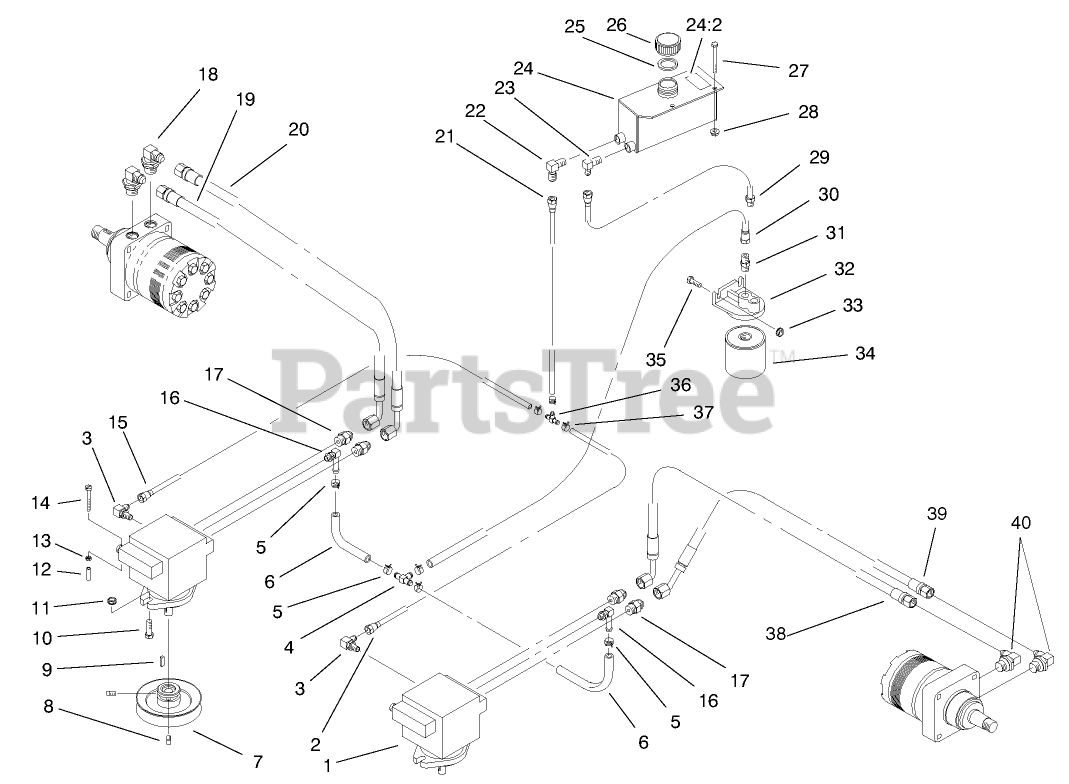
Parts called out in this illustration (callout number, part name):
1	Pump-Hydro
2	Hose-Low Pressure
3	Elbow
4	Fitting
5	Clamp-Hose
6	Hose-Low Pressure
7	Sheave w/Hub
8	SCREW-SET, SQH
9	Key
10	SCREW-HH
11	NUT-HHF, WHIZ
12	Grip
13	NUT-LOCK, NI
14	Screw-PPH
15	Hose-Low Pressure
16	Elbow
17	Adapter
18	Elbow 90
19	Hose
20	Hose
21	Hose
22	Elbow
23	Elbow
24	HYDRAULIC TANK ASM
24:2	Decal-HydraulicTank, Hot Surface
25	Gasket
26	Cap
27	SCREW-HH
28	NUT-HF
29	Hose
30	Hose
31	Connector
32	Head-Filter
33	NUT-HF
34	Filter-Hydro
34	Filter-Winter
35	SCREW-HH
36	Fitting
37	Clamp-Hose
38	OBS HOSE-HYD
39	OBS HOSE-HYD
40	Elbow
